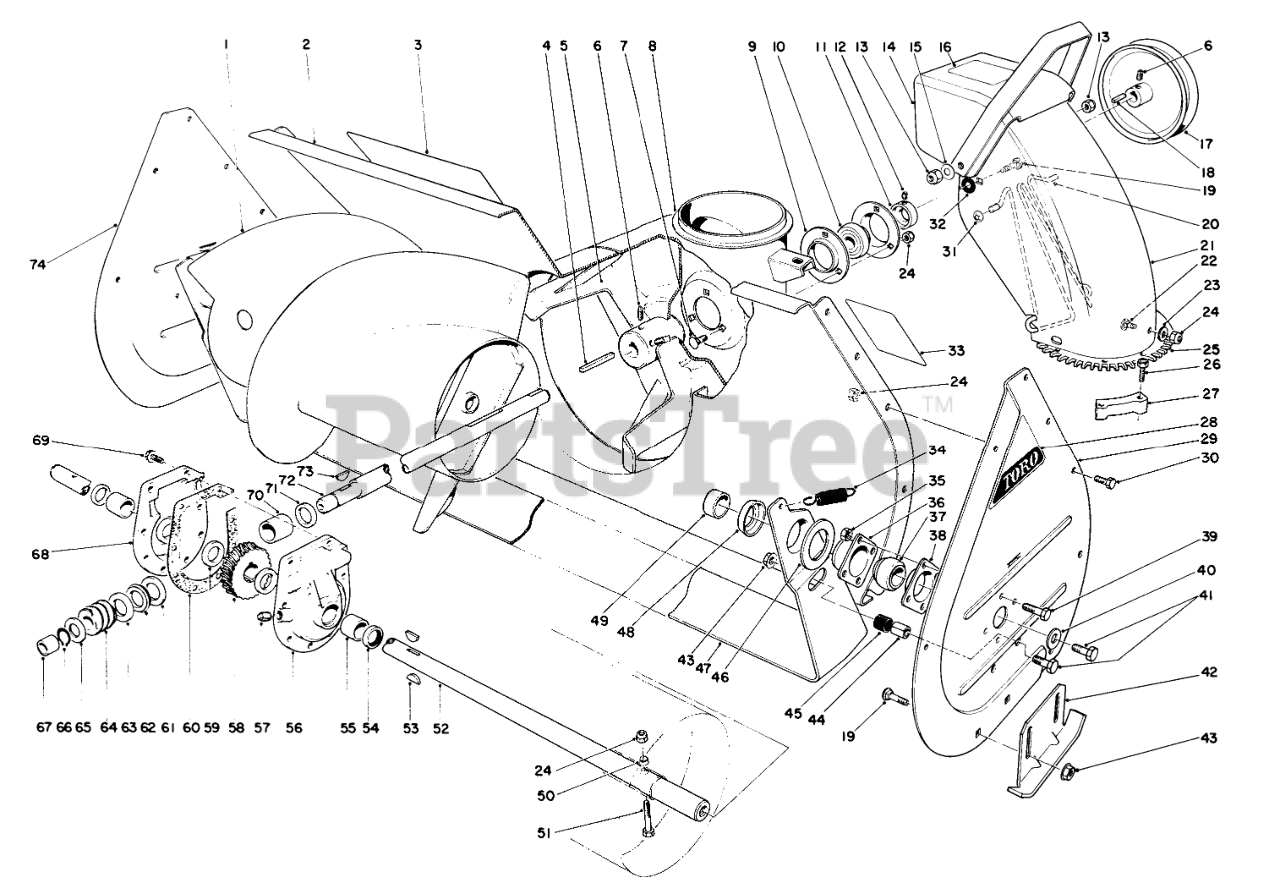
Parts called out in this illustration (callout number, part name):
1	RH AUGER WA 26" B
2	AUGER HSG WA 26" R
3	AUGER WARNING DECAL
5	IMPELLER ASM
6	SCREW-SET, SQH
7	BOLT-CARR
8	CHUTE RING
9	BRG FLANGE
10	BALL BRG W/COLLAR
11	EXT LOCKING COLLAR
12	SCREW-HSH
13	NUT-LOCK, CONE
14	Deflector (Incl. Ref. #16)
15	WASHER-BELLEVILLE
16	Decal-Danger
17	1/2 X 9.5 DIA PULLEY
18	SQUARE KEY
19	SCREW-CARR
20	CHUTE WIRE
21	Upper Chute
22	SCREW-CARR
23	WASHER-PLAIN
24	NUT-LOCK, NI
25	Screw
26	SCREW-SPECIAL
27	RETAINER-CHUTE
28	AUGER SIDE PLT DECAL
29	LH AUGER SIDE PLT R
30	SCREW-HH
31	NUT-PUSH
32	WASHER-RUBBER
33	DECAL-WARNING, AUGER
34	SPRING-TENSION
35	NUT-LOCK, CONE
36	BEARING-FLANGE, FRONT
37	BEARING
38	BEARING-FLANGE, REAR
39	SCREW-HH
40	WASHER
41	SCREW-HH
42	AUGER SKID WA R
43	NUT-HF
44	SCRAPER STOP SPACER
45	SCRAPER STOP CUSHION
46	SCRAPER BLADE SPACER
47	SCRAPER BLADE 26 R
48	Positioner-Scraper
49	AUGER SPACER
50	SPACER-HUB, AUGER
51	Auger Bolt
52	26 AUGER SHAFT
53	KEY-WOODRUFF
54	SEAL-OIL
55	BUSHING
56	Bear Case L.H. (Incl. Ref. #54-55)
57	PLUG-PIPE, SQH
58	GEAR-WORM, 27T
59	WASHER-THRUST
60	GASKET-CASE, GEAR
61	WASHER-THRUST
62	BEARING-THRUST
63	THRUST-WASHER
65	WASHER-THRUST
66	Ring-Snap
67	BUSHING
68	Gear Case R.H. (Incl. Ref. #54-55)
69	SCREW-TAPTITE
70	BUSHING-SPECIAL
71	RING-QUAD
72	SHAFT-IMPELLER
73	KEY-WOODRUFF
74	RH AUGER SIDE PLT R
